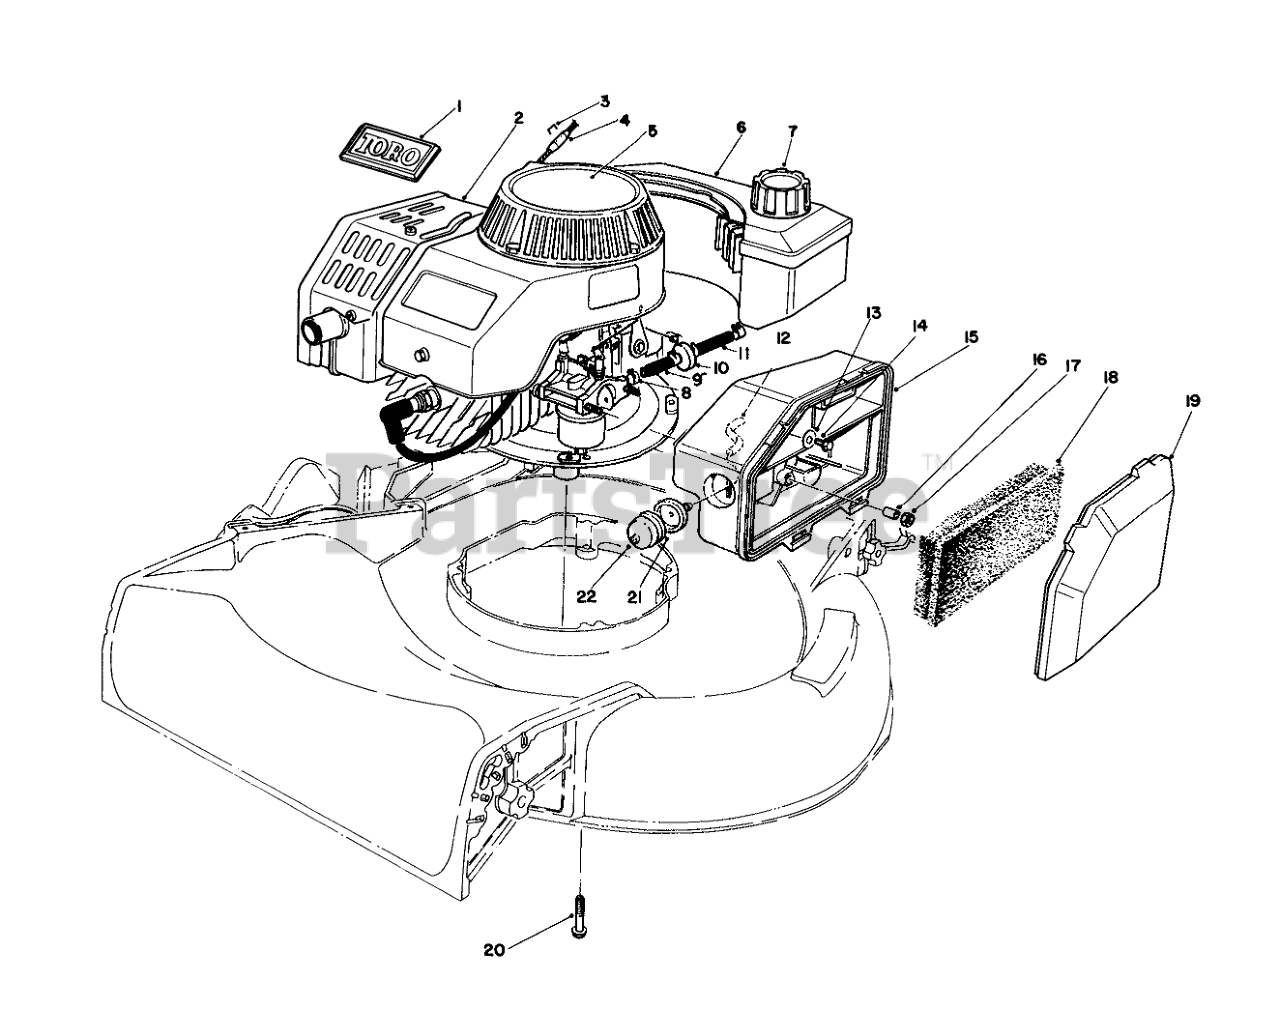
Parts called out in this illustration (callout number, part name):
1	TORO LOGO PLT
2	Engine
3	Staple
4	STOP-ROPE
5	DECAL
6	Fuel Tank Assembly
7	GAS CAP ASM
8	CLAMP-FUEL LINE
9	HOSE-FUEL
10	FILTER-FUEL
11	HOSE-FUEL
12	HOSE-PRIMER
13	WASHER-FLAT
14	SCREW-HH
15	BODY-AIR CLEANER
16	SPACER
18	ELEMENT-AIR CLEANER
19	COVER-AIR CLEANER
20	SCREW-HHF, WHIZ
21	BODY-PRIMER
22	Bulb Primer
23	Fuel Filter Kit (Incl. Ref. #8-11
